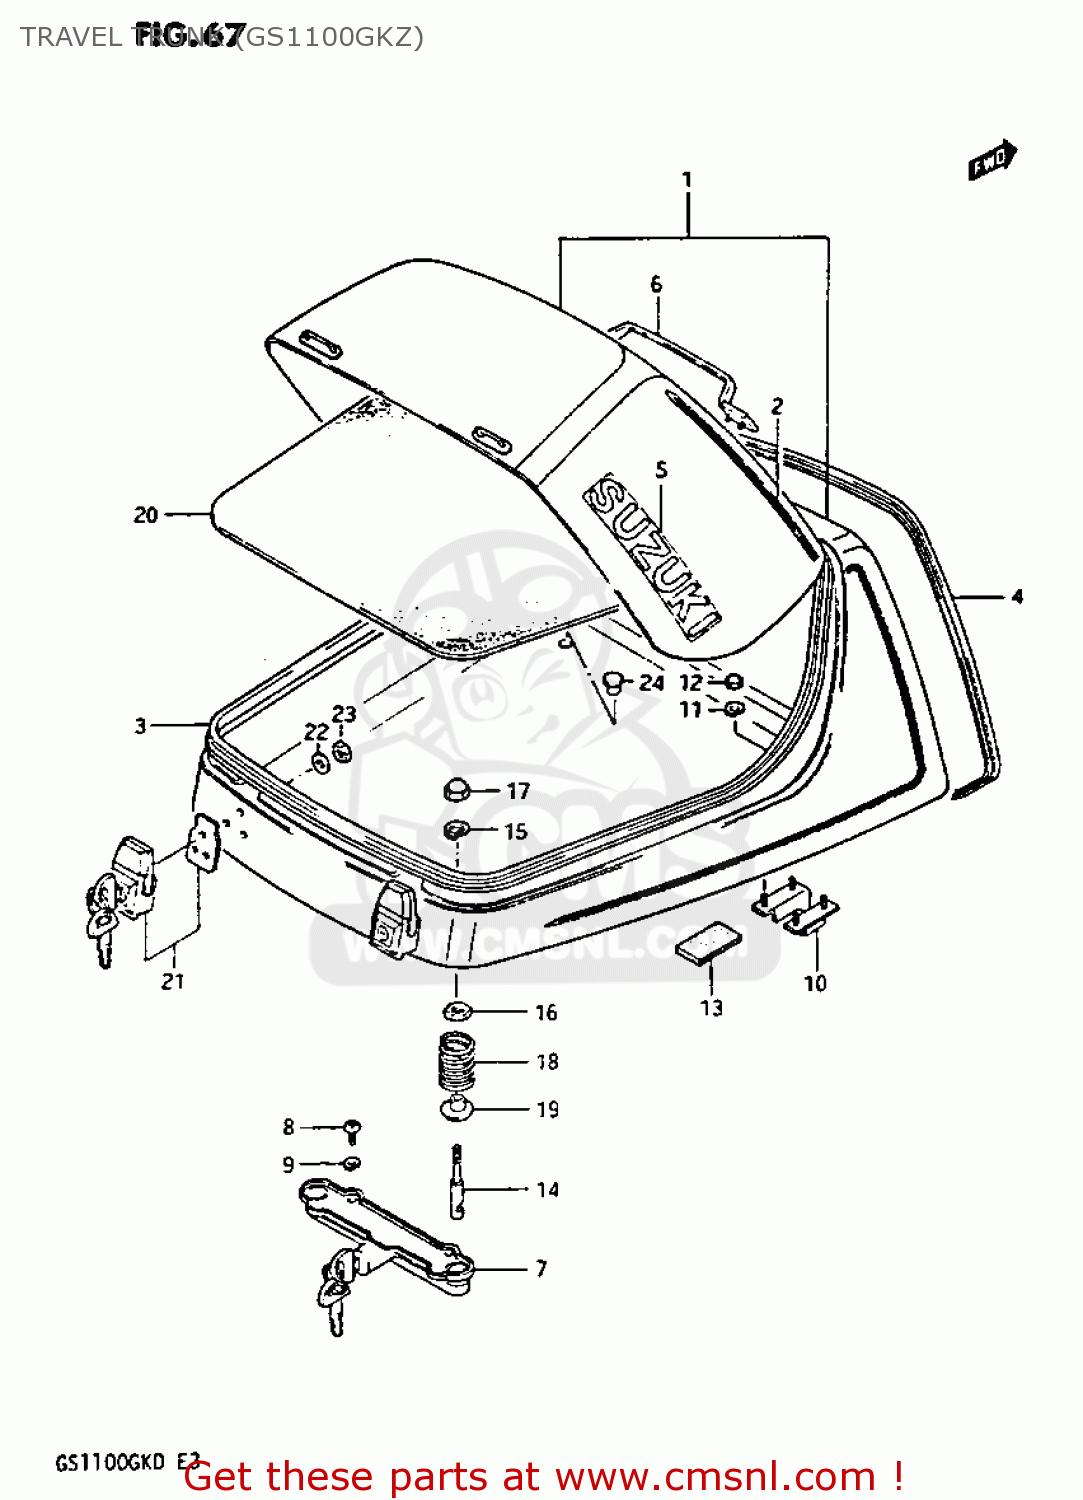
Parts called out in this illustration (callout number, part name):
1	TRAVEL TRUNK (BLACK)
2	TAPE SET,COWLING BODY
3	SEAL,TRAVEL TRUNK
4	MOLDING,TRAVEL TRUNK
5	EMBLEM,COWLING
6	GRIP TRAVEL TRUNK
7	LOCK,TRAVEL TRANK
8	SCREW 6X12
9	WASHER,LOCK
10	HOOK COMP TRAV TRUNK
11	LOCK WASHER
12	NUT
13	CUSHION TRAVEL TRUNK
14	LOCK BOSS TRAV TRUNK
15	WASHER,LOCK
16	NUT
17	NUT
18	SPRING,TRAVEL TRUNK
19	GUIDE,TRAVEL TRUNK SPRING
20	CUSHION TRAVEL TRUNK
21	LOCK,TRANK LID
22	WASHER 4MM
23	NUT 4MM
24	PLUG(OD:14)
